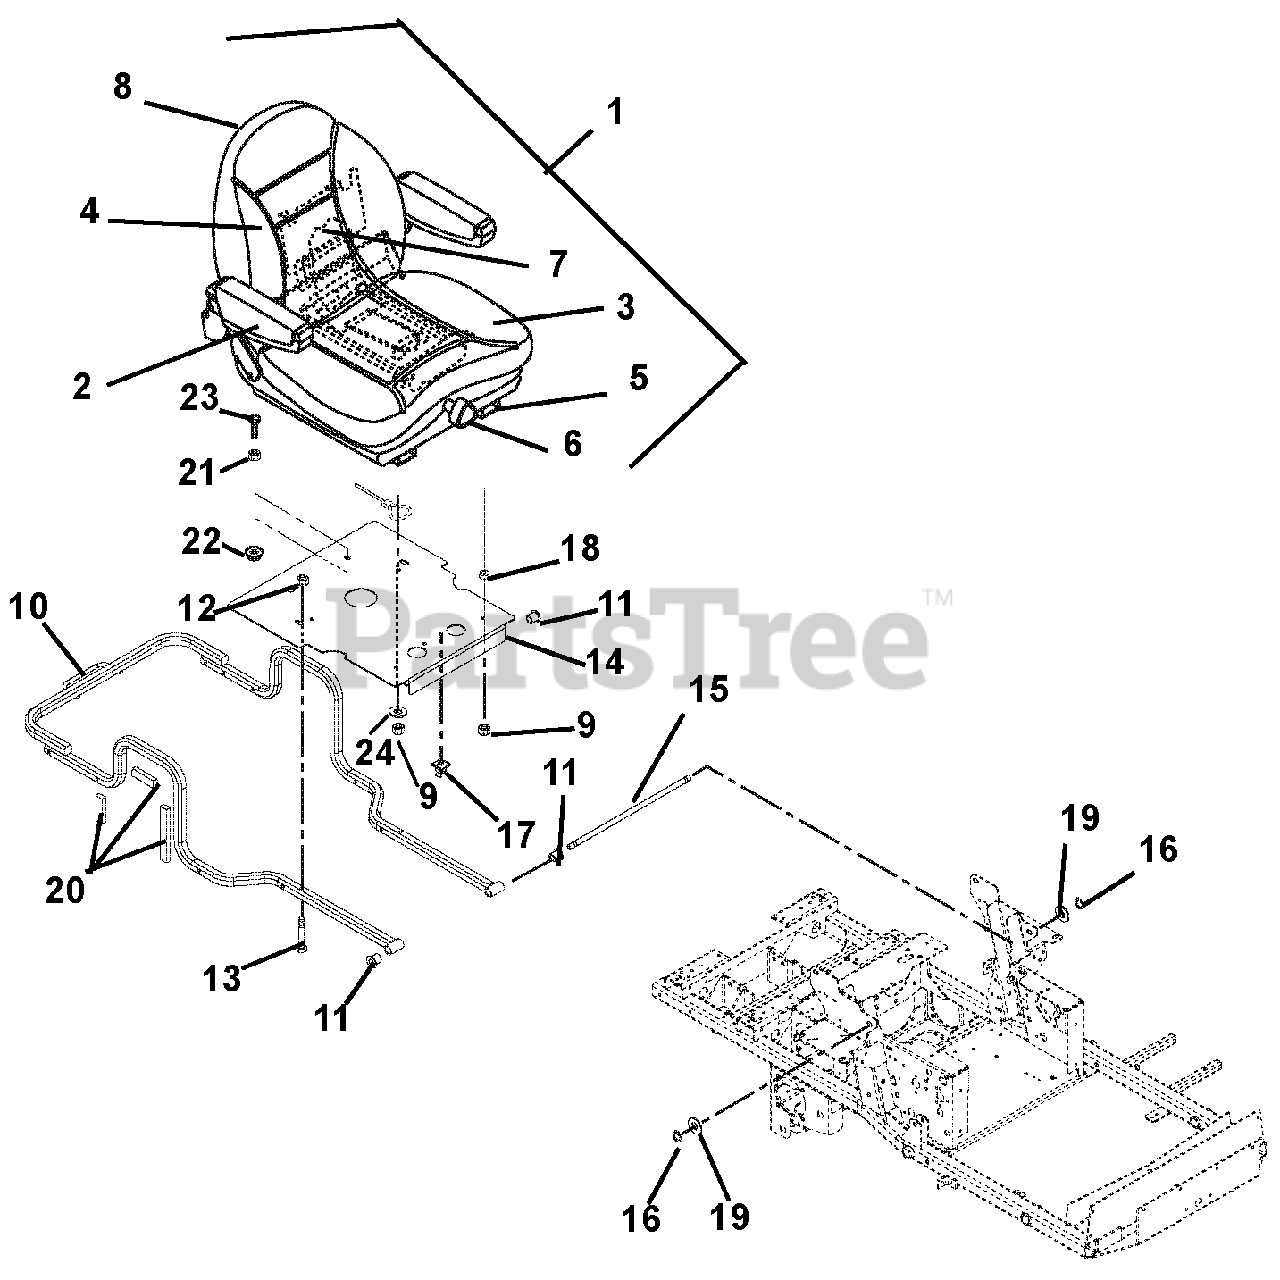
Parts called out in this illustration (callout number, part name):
1	Seat, Suspension, Light Gray
2	Kit, Arm Pad (1 per bag)
3	Kit, Seat Cushion, Light Gray
4	Kit, Back Cushion, Light Gray
5	Kit, Seat Slide
6	Kit, Seat Knob
7	Kit, Spring and Saddle
8	Kit, Seat Back Panel
9	Nut, Locking Top Flange .31-18
10	Weldment, Hood Frame
11	Bushing, Flange .515 x .750 x .745 x 1.00
12	Nut, Locking Top Flange .38-16
13	Bolt, Rib Neck .38-16 x 1.50
14	Weldment, Seat Pivot Mount
15	Rod, Seat Frame Pivot
16	Ring, Retaining External .500 x .050
18	Bushing, Sleeve .377 x .624 x .235
19	Washer, Flat Steel .531 x 1.06 x .095
20	Tape, VHB
21	Nut, Hex .50-13
22	Nut, Locking Top Flange .50-13
23	Bolt, Hex .50-13 x 1.50
24	Washer, Flat Steel .344 x 1.125 x .135
